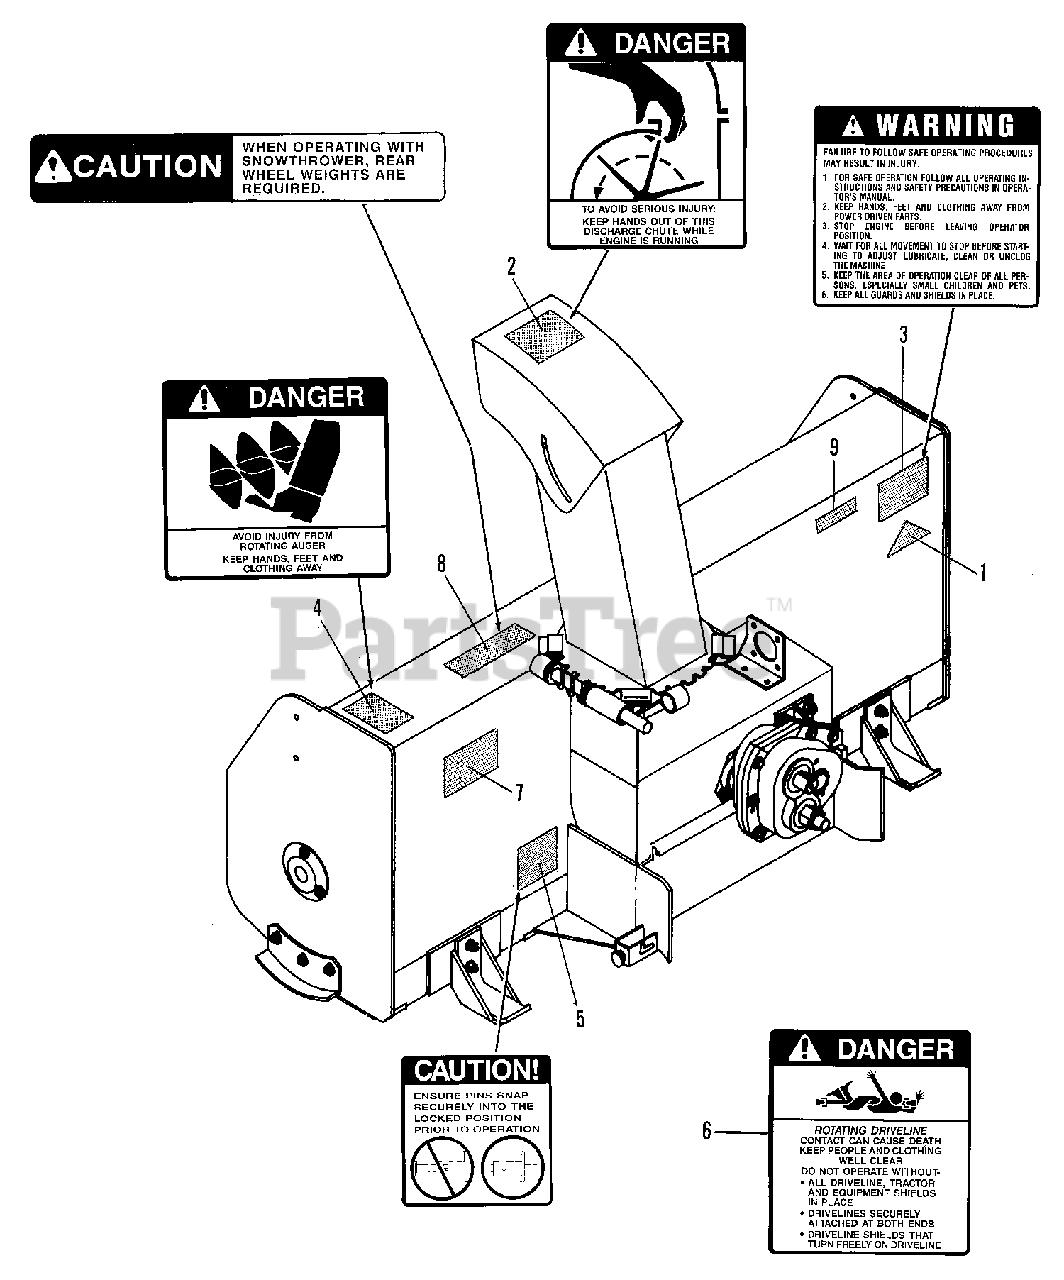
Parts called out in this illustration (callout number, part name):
1	DECAL, OPEI (Not Serviced)
2	DECAL, Danger, Blower
3	DECAL, Caution
4	DECAL, Danger, Auger
5	DECAL, Danger, Shot-Pins
6	DECAL, Danger, Rotating Driveline
7	DECAL, Important, Shear Bolt
8	DECAL, Caution, Rear Wheel Weights
9	DECAL, I. D. Plate (Not Serviced)
